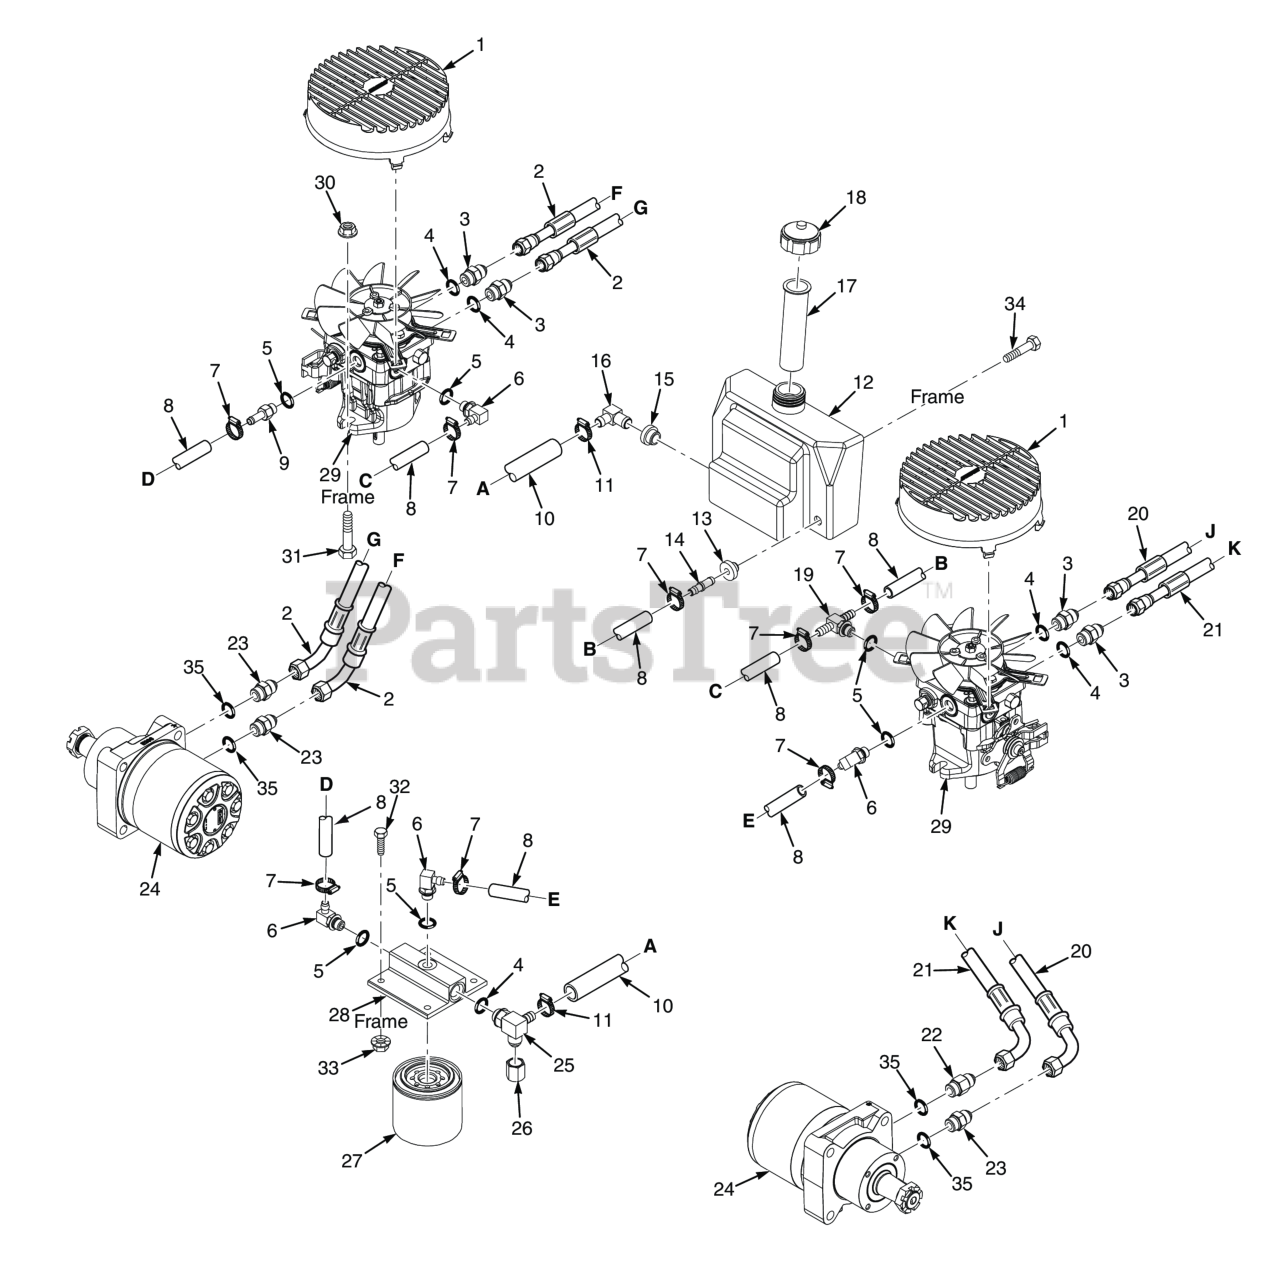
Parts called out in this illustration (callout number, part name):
1	Fan Cover, Pump
2	Hose Assembly
3	Union, 3/4"-16 JIC x 3/4"-16 O-Ring
4	"O" RING, 3/32 X 5/8" ID
5	"O" RING, 5/64 X 15/32 ID
6	Elbow, 90 Degree - 9/16" O-Ring x 3/8" Hose
7	Clamp, .69" Max. / .25" Min. Dia.
8	Hose, 3/8" ID - 10-1/4" Long (Order By The Inch)
9	Fitting, 9/16" O-Ring x 3/8" Hose
10	Hose Assembly, 1/2" ID (Oil Reservoir to Filter Base)
11	Clamp, Cable 3/4" I.D.
12	Hydraulic Tank Assy
13	Bushing, 0.56" Dia. Viton
14	Fitting, Straight
15	Bushing, 0.78" Dia. Viton
16	Fitting, 90 Degree - 1/2" Hose
17	Insert, Filler Neck
18	CAP, HYDRAULIC TANK
19	Tee Fitting, O-Ring to Barb
20	Hose Assembly
21	Hose Assembly
22	Fitting, 1/2" JIC x 5/8" O-Ring (LH Wheel Motor - Upper Port Only)
23	TUBE UNION, 3/4-16 JIC TO 7/8-14 "O" RING
24	Wheel Motor, Parker
25	Tee, 3/4" O-Ring x JIC x 1/2" Hose
26	CAP, 3-4-16 JIC
27	OIL FILTER, SPECIAL
28	Filter Head Assembly
29	Pump, LH (PK-3KCC-GA1F-XXXX)
29	Pump, RH (PK-3HCC-GA1F-XXXX)
30	Nut, Flange Elastic Stop Nut, 3/8-16
31	Bolt, Hex Head, 3/8-16 x 1-1/2"
32	BOLT, SERRATED FLANGE HEX HEAD 5/16-18 X 3/4"
33	Nut, Serrated Flange 5/16-18 (Right Front Engine Mounting, Briggs and Kohler Only)
34	CAP SCREW, 5/16-18 X 1/2" SERRATED FLANGE HEX
35	"O" RING, 3/32 X 3/4 ID
